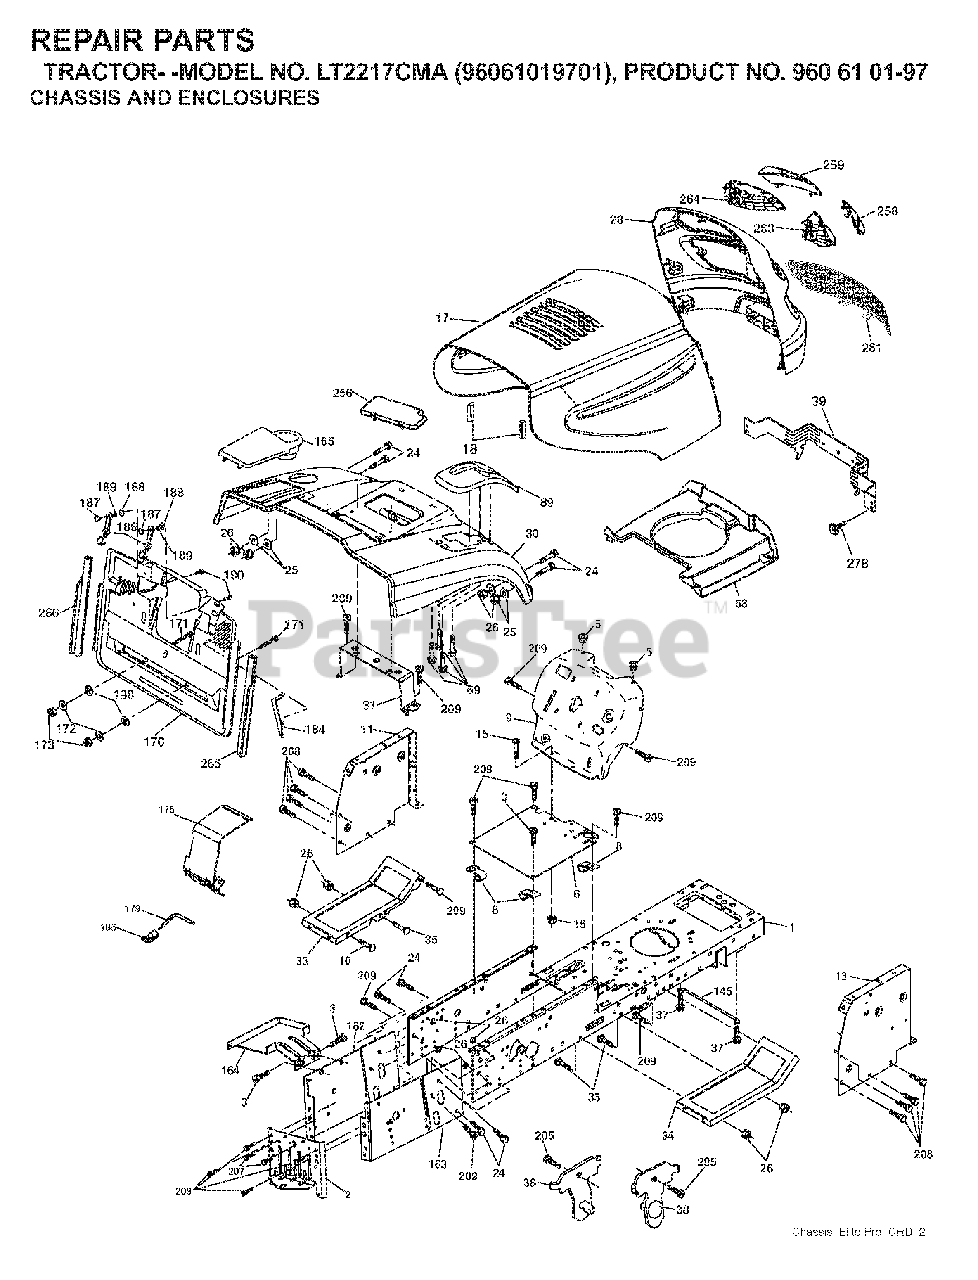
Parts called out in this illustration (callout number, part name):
1	CHASSIS
3	SCREW 3/8-16X3/4
5	BUMPER.RUBBER.HOOD
8	CLIP,INSULATOR
10	BOLT D
11	PANEL.DASH.LH.LTX
13	PANEL DASH RH
16	NUT
18	BUMPER.HOOD.LARGE.1.75"
24	BOLT
25	WASHER
26	NUT
31	BRACKET SUPPORT FENDER
35	BOLT
37	SCREW LT
39	BRACKET PIVOT
69	SCREW.HI-LO.CONSOLE
145	ROD.PIVOT.HOOD
164	SUPPORT
171	BOLT
172	WASHER
186	LATCH ASSY
187	WELDNUT
189	LOCKWASHER
190	SCREW
205	SCREW LT
207	SCREW, 5/16-18 X 1/2
208	SCREW 3/8-16X1/2
209	SCREW, 3/8-16X3/4
263	BEZEL GRILL RH
264	BEZEL GRILL LH
278	SCREW
